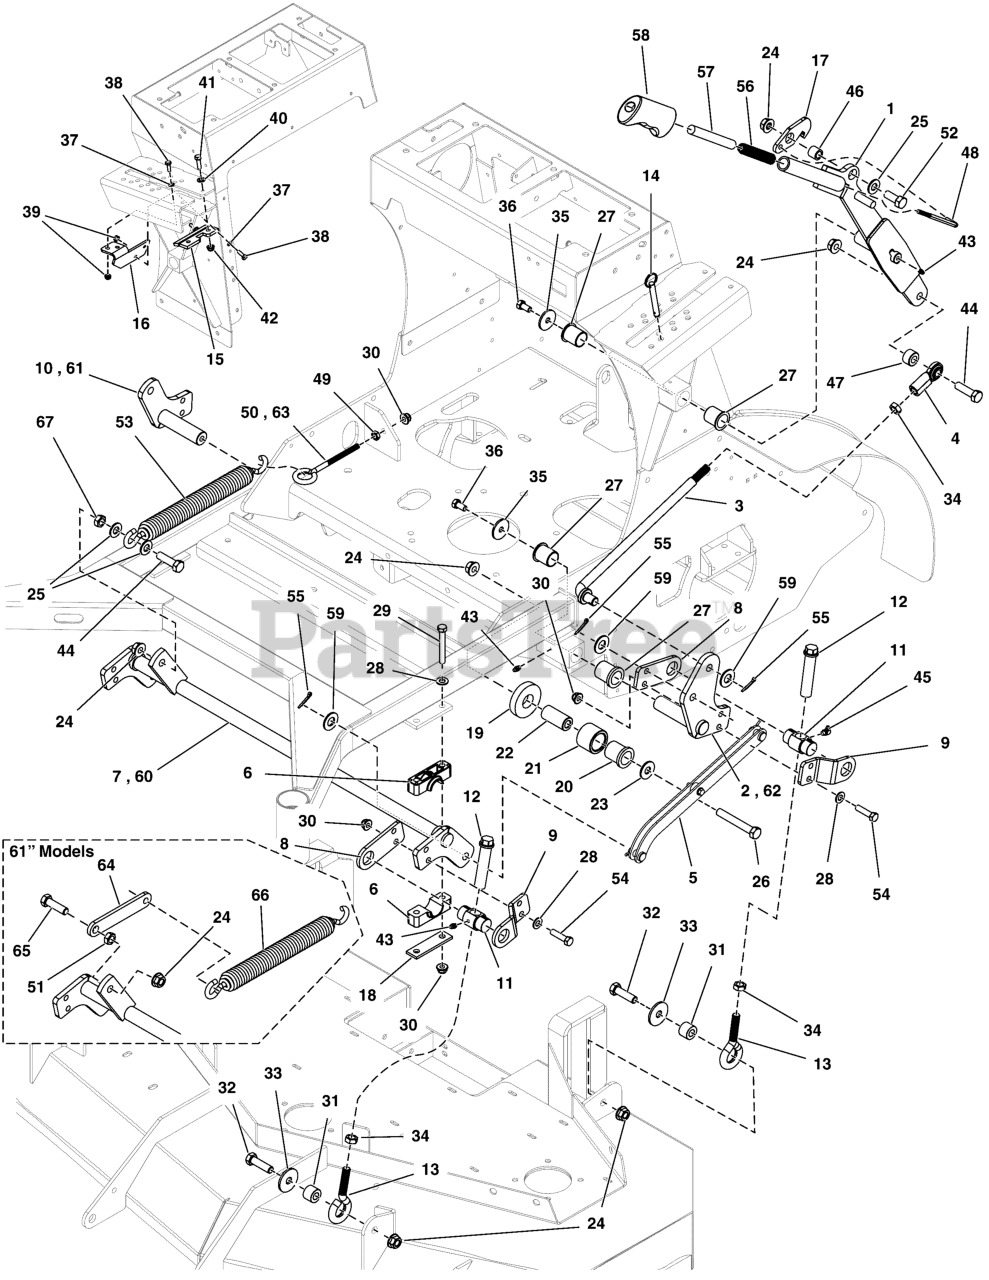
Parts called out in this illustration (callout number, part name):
1	WELD, DECK LIFT, STAND ON - BLK
2	WELD, REAR DECK LIFT PIVOT, LH - BLK
3	ROD, MAIN DECK LIFT, STAND-ON
4	JOINT-BALL .500-20 THD .500ID, CLR ZINC
5	Refer to: Deck Lift Group - Deck Timing Plates
6	PIVOT BLOCK, PLASTIC
7	WELD, SHAFT, DECK LIFT - BLK
8	BRACKET, INNER TRUNION MNT - BLK
9	BRACKET, OUTER TRUNION MNT - BLK
10	WELD, RH REAR PIVOT, STAND ON - BLK
11	PIVOT, DECK LIFT TRUNION, GREASABLE
12	ADJUSTER, HEIGHT
13	EYE BOLT, 1/2-20 X 4.25,1.88THRD,1EYE,CZ
14	PIN, HITCH, 3/8" DIA X 2.5" EL, CZ
15	PLATE, LATCH GUIDE - BLK
16	PLATE, BRACKET, DECK LIFT SUPPORT - BLK
17	PLATE, LATCH, PUSH BUTTON LIFT - BLK
18	PLATE, PIVOT BLOCK SUPPORT - BLK
19	WASHER, FRICTION
20	BUSHING, FLANGE
21	ROLLER, DECK HEIGHT
22	SPACER, .52 X 1.00 X 2.09 - SS
23	WASHER, 1/2" USSZ
24	NUT, Hex Flange, Nylock, 1/2-13
25	WASHER, 1/2 SAE
26	BOLT, 1/2-13 X 3-1/4, HEX HD, GD5, CZ (SV)
27	BUSHING, 1.00 X 1.13 X 1.38, Plastic
28	WASHER, 3/8 SAE
29	BOLT, 3/8-16 X 2-3/4" GD5 CZ
30	NUT, 3/8 - 16 HEX NYLOCK FLANGE
31	SPACER, .52 X 1.00 X .75, CZ
32	BOLT, 1/2-13 X 1-3/4 GD5 CZ
33	WASHER, .52 X 1.75 X .14, CZ
34	NUT, 1/2-20 Hex Jam
35	WASHER, .390 X 1.50 X .109, YZ
36	BOLT, 3/8-16 X 3/4, PLT W/PATCH
37	WASHER, 1/4 SAE
38	BOLT, 1/4"-20 X 3/4" GD5 YZ
39	NUT, 1/4-20 Hex Nylock Flange
40	WASHER, 5/16" SAE
41	BOLT, 5/16-18 X 1" GRD5 YZ
42	NUT, 5/16-18 HEX NYLOCK FLANGE NUT
43	GREASE FITTING, 1/4-28 Straight
44	BOLT, 1/2-13 X 2-1/4" GD5 CZ
45	GREASE FITTING, 1/4-28 STRAIGHT, 90 DEGREE
46	SPACER, .50 X .75 X .66, CZ
47	SPACER, .52 X 1.00 X .63, YZ
48	ROD, DECK LIFT LATCH
49	NUT, 3/8-16 HEX JAM
50	EYE BOLT, 3/8-16 X 6, 3THRD, 1EYE, CZ
51	NUT, Hex, Jam, 1/2-13
52	BOLT, 1/2-13 X 1-1/2 GD5 CZ
53	SPRING-EXT, 1.393 ODX13.25LGX.218WR, BLK
54	BOLT, 3/8-16 X 1-1/2" GD5 CZ
55	PIN, COTTER, 1/8 X 1-1/4
56	SPRING-COMP 0.715ODX 03.85 LG
57	BUTTON, PUSH, DECK LIFT, THREADED
58	GRIP,LIFT LEVER
59	WASHER, 5/8" SAE
60	WELD, SHAFT, DECK LIFT - BLK
61	WELD, RH REAR PIVOT, SRSZ2-61 - BLK
62	WELD, LH REAR PIVOT, SRSZ2-61 - BLK
63	EYE BOLT, 3/8-16 X 6.88, 3THRD, 1EYE
64	PLATE, SPRING LINK, SRS Z2, 61 - BLK
65	BOLT, 1/2-13 X 2" GD5 CZ
66	SPRING, EXT, 1.5ODX12.25X.234WIRE BLK
67	NUT, 1/2-13 HEX, YZ
